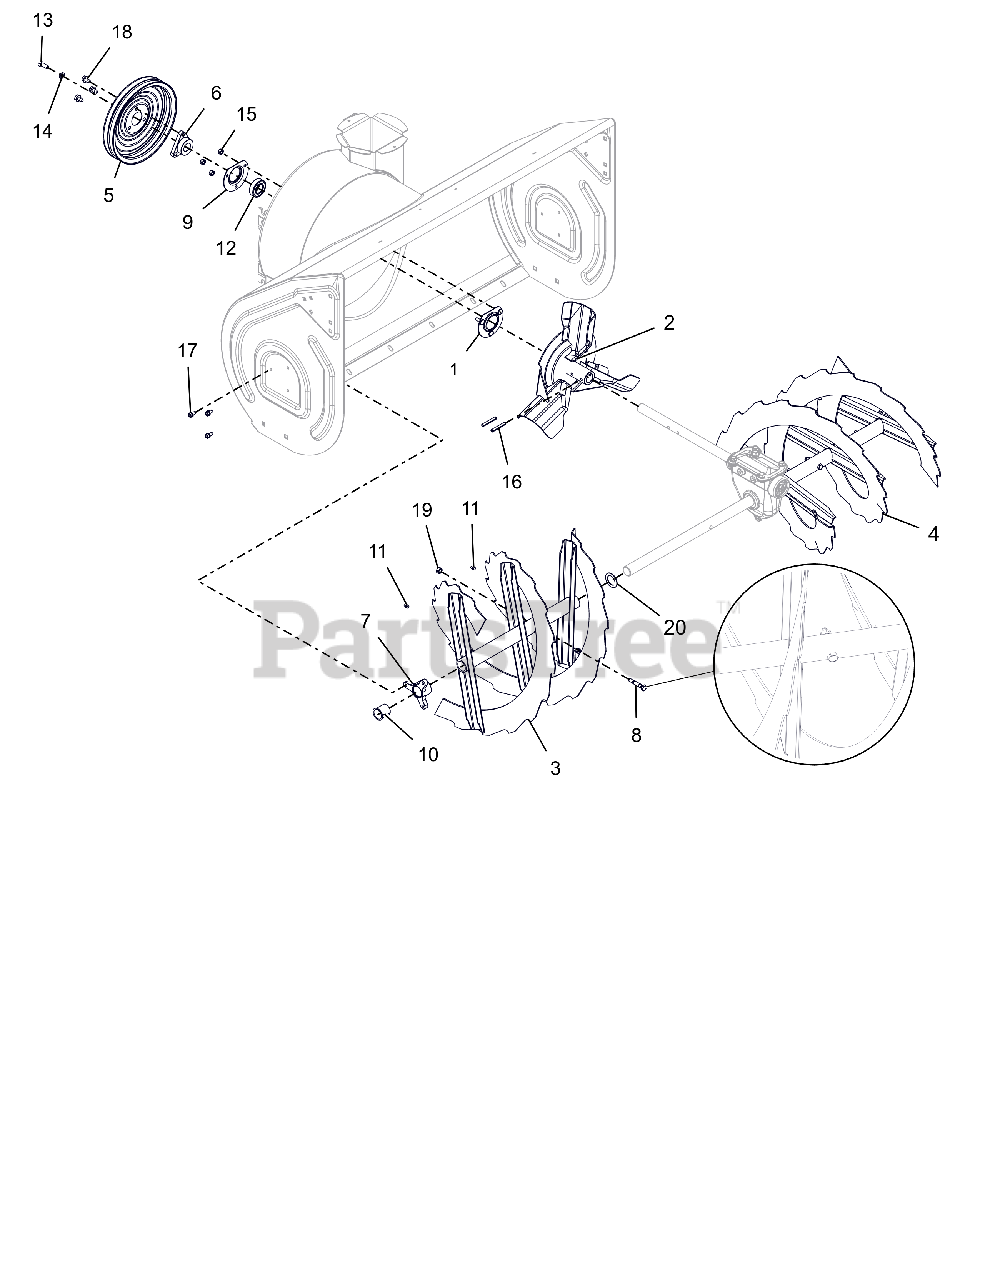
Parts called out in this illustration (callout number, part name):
1	BEARING FLANGE
2	IMPELLER, 3 BLADE-14"
3	RAKE, RH-36"(1 ID X 15.75 OD)
4	RAKE, LH-36" (1 ID X 15.75 OD)
5	PULLEY, SPIN FORM DUAL GROOVE
6	PULLEY HUB, D-BORE .87 PRO
7	BUSHING, RAKE SHAFT 1"
8	BOLT, SHEAR - DELUXE
9	BEARING FLANGE
10	BSHG-FLG SPLIT NYLINER 1.0" HP
11	ZERK,FITTING .25X.125 DRIVE IN
12	BRG-BALL .876X1.75X.50 RSTFP
13	BLT-HEX .31-24X.75 YWZC GR5
14	WSHR-LK .312X.097 HVY YWZC
15	@NUT-LK-CTR .25-20 YWZC
16	PIN-ROLL .250X1.75
17	SCR-TAP .25-20X.50 HWH TR YWZ
18	@SCR-TAP .31-18X.50 HWH TR YWZ
19	@NUT-LK-CTR .31-18 YWZC
20	WSHR-FL-STL 1.010X1.505X.062YZ
